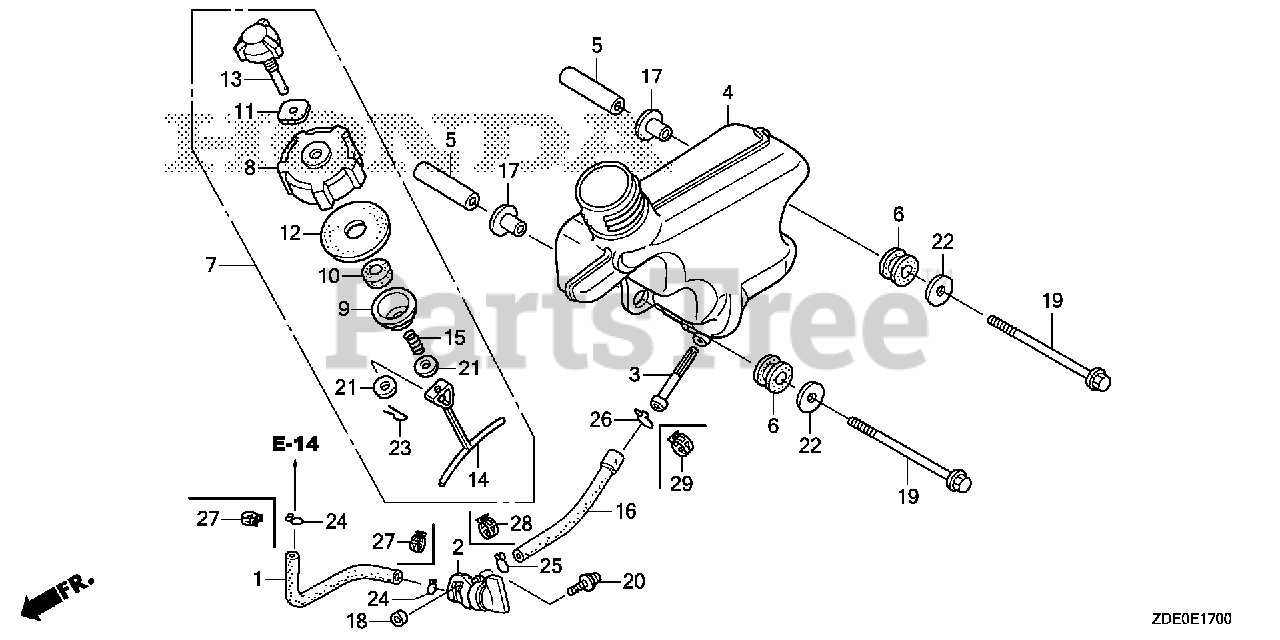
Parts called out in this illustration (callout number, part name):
1	TUBE B, FUEL (FKM)
2	PETCOCK ASSY.
3	FILTER, FUEL
4	TANK, FUEL
5	COLLAR, TANK SETTING
6	RUBBER A, TANK MOUNTING
7	CAP ASSY., FUEL TANK
8	BODY, FUEL CAP
9	INNER, FUEL CAP
10	SPONGE, FUEL CAP BREATHER
11	GASKET, VALVE
12	GASKET, FUEL CAP
13	VALVE, BREATHER
14	LINK, FUEL CAP
15	SPRING, FUEL CAP
16	TUBE, FUEL (FKM)
17	COLLAR, CANISTER MOUNTING
18	COLLAR, FR. TURN SIGNAL
19	BOLT, FLANGE (6X65)
20	SCREW-WASHER (5X10)
21	WASHER, PLAIN (4MM)
22	WASHER, PLAIN (6MM)
23	PIN, LOCK (4MM)
27	CLIP, TUBE (D8)
28	CLAMP, TUBE (D10)
29	CLAMP, TUBE (D12)
